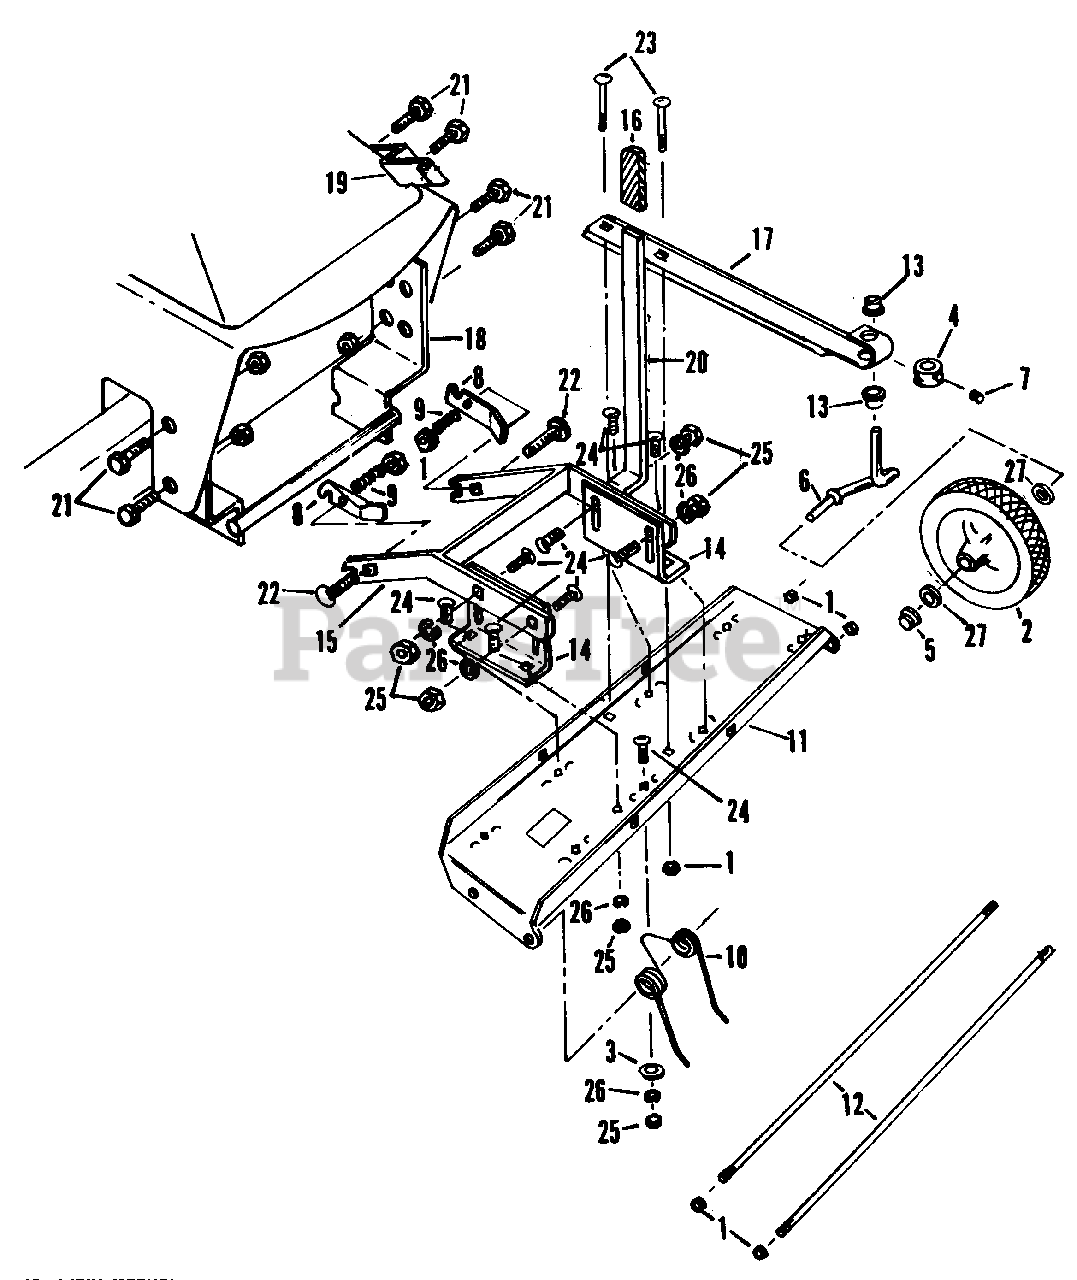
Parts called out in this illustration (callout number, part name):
1	1/4" Hex lock nut
1	FOOT, right hand
2	Gauge wheel
2	FOOT, left hand
3	5/16" Special washer
3	GUARD, FOOT POCKET, right hand
4	Locking collar
4	GUARD, FOOT POCKET, left hand
5	Push nut
5	FRAME, FRONT PANEL
6	BRACE, FRONT PANEL FRAME
7	5/16" Set screw
7	SUPPORT, CHUTE CONTROL CRANK
8	Frame latch
8	BRACKET, REAR ATTACHING, right hand
9	Compression spring
9	BRACKET, REAR ATTACHING, left hand
10	Thatching tine
10	PLATE, REAR ATTACHING
11	Tine tray
11	CROSS BAR, REAR
12	Safety rod
12	POST, FRONT, right hand (straight w/screw)
13	1/2" Nylon bearing
13	POST, FRONT, left hand (straight w/screw)
14	Tray bracket
14	BRACE, TOP, right hand
15	Main frame
15	BRACE, TOP, left hand
16	Handle grip
16	TOP FRAME, HTS
17	Wheel support
17	POST, REAR CORNER, right hand
18	Frame mounting bracket
18	POST, REAR CORNER, left hand
19	Transport lock
19	"L" BRACKET
20	Lift handle
20	3/4" LOOP
21	3/8" x 1" Hex bolt
21	FRONT PANEL VINYL
22	1/4" x 1-1/4" Carriage bolt
22	WINDSHIELD
23	1/4" x 1-3/4" Carriage bolt
23	DOOR, right hand
24	5/16" x 1" Carriage bolt
24	DOOR, left hand
25	5/16" Hex nut
25	REAR CURTAIN
26	5/16" Lock washer
26	TOP, FIBERGLASS, HTS (trim)
27	1/2" Plain washer
27	CRANK, CHUTE CONTROL
28	PARTS BAG (contents listed below)
29	1/4"-20 LOCKNUT
30	DOOR HINGE
31	1/4"-20 x 3/4" BOLT
32	SPRING, DOOR LATCH
33	1/4" FLAT WASHER
34	5/16"-18 x 1-1/2" BOLT
35	3/8"-16 LOCKNUT
36	3/8"-16 x 3/4" BOLT
